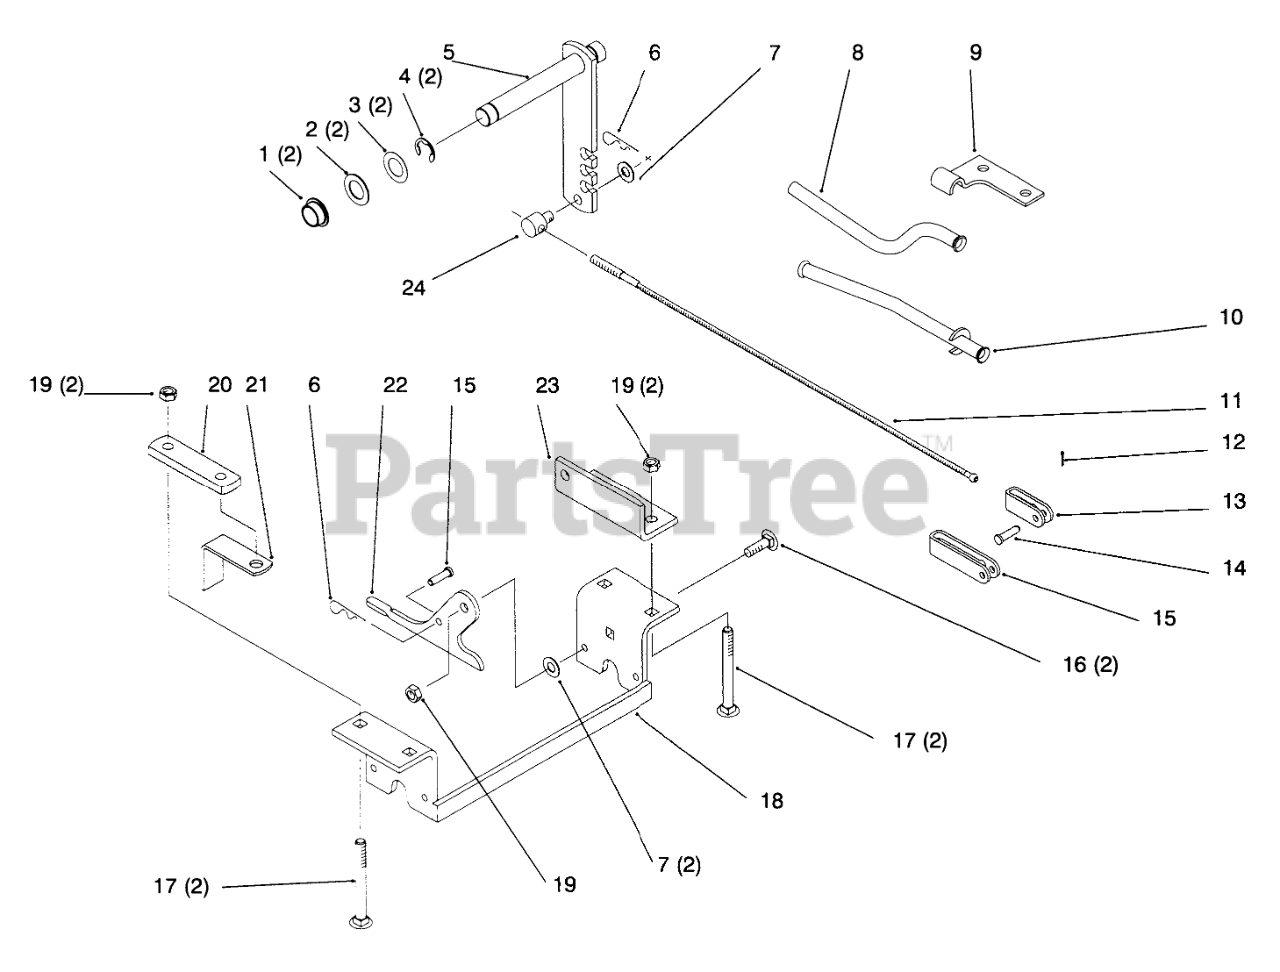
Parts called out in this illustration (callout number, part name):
1	BUSHING-BRONZE
2	WASHER
3	WASHER-SHIM
4	E-RING
5	ASSY LEVER R
6	PIN-HAIR
7	WASHER-FLAT
8	TUBE-CONDUIT R
9	CLAMP-CONDUIT R
10	TUBE ASSY COMPLET R
11	CABLE
12	PIN-COTTER
13	CLEVIS-SHORT
14	PIN-CLEVIS
15	CLEVIS-LONG
16	BOLT-CARR
17	SCREW-CARR
18	Bracket
19	NUT-HEX
20	BRACKET-REAR LINK MOUNTING
21	SPACER-BRACKET
22	PLATE-LATCHING
23	LINK-BRACKET R
24	TRUNNION-CLUTCH ROD
